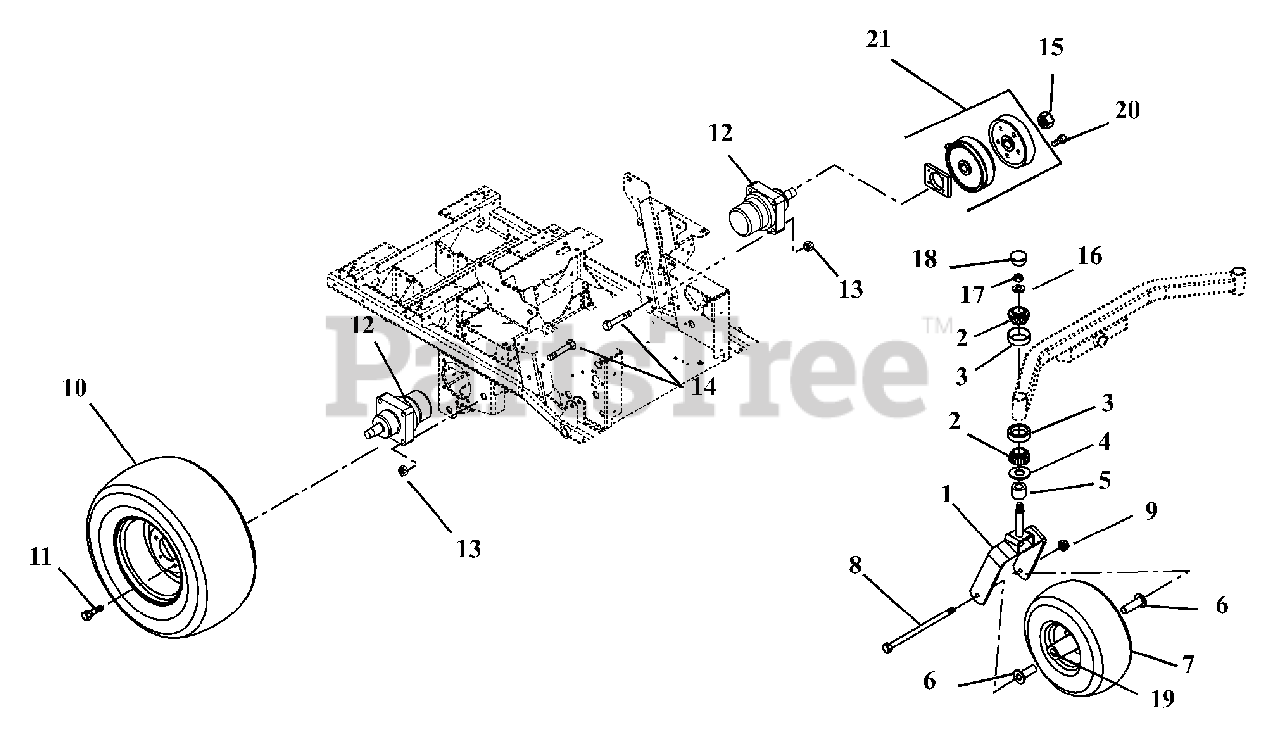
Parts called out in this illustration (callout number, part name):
1	FORK - FRONT
2	BRG, CONE W/ GREASE
3	BRG-CUP1.980X.420
4	BEARING SEAL 1.5 X 2 X .18
5	SPACER 1.005X1.5075X.375
6	SPACER - WHEEL
7	WHEEL/TIRE ASM
8	@BLT-HEX .50-13X9.00 GR5 YWZC
9	@NUT-LK-CTR .50-13 YWZC
10	TIRE/WHEEL ASSY 24X12-12
11	BLT, LUG .50-20 X 1.38
12	MOTOR, PARKER WHEEL
13	@NUT-LK-TOP-FLG .50-13 YWZC
14	BOLT, WHEEL MOTOR 1/2-13X2.75
15	NUT-LK-JAM-PTCH 1.00-20
16	@WSHR-FL-STL.812X1.50X.135YWZC
17	NUT-JAM CTRLK .75-16 YWZC
18	CAP,DUST
19	BRG, 25MM ID X 52MM OD X 15MM
20	@BLT-HEX .31-18X1.50 GR5 YWZC
21	KIT, BRAKE SERVICE (1-SIDE)
